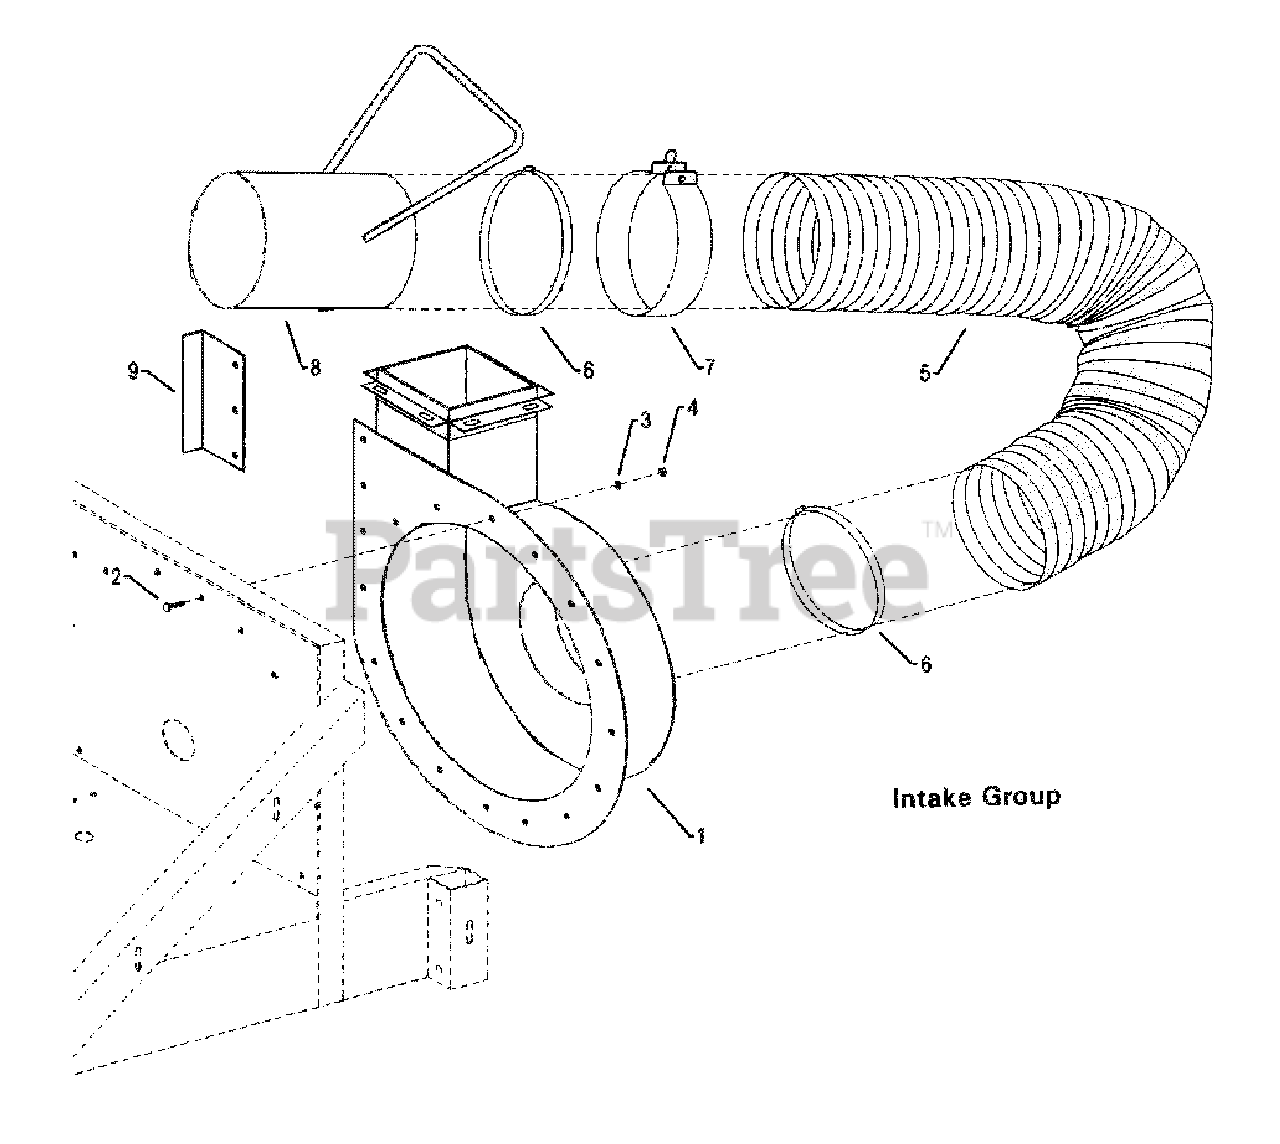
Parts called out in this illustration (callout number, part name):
1	Housing, Impeller - Complete with Liner Kit Below
2	3/8-16 x 1" Hex Bolt
3	3/8 Lock Washer
4	3/8-16 Hex Nut
5	Hose, Intake 12" x 10'
6	Clamp, Hose 12"
7	Band, Hose Support 12" with Hardware
8	Nozzle, Intake 12" w/Adjustable Handle
9	Plate, Hose Protector (CHW Units Only)
